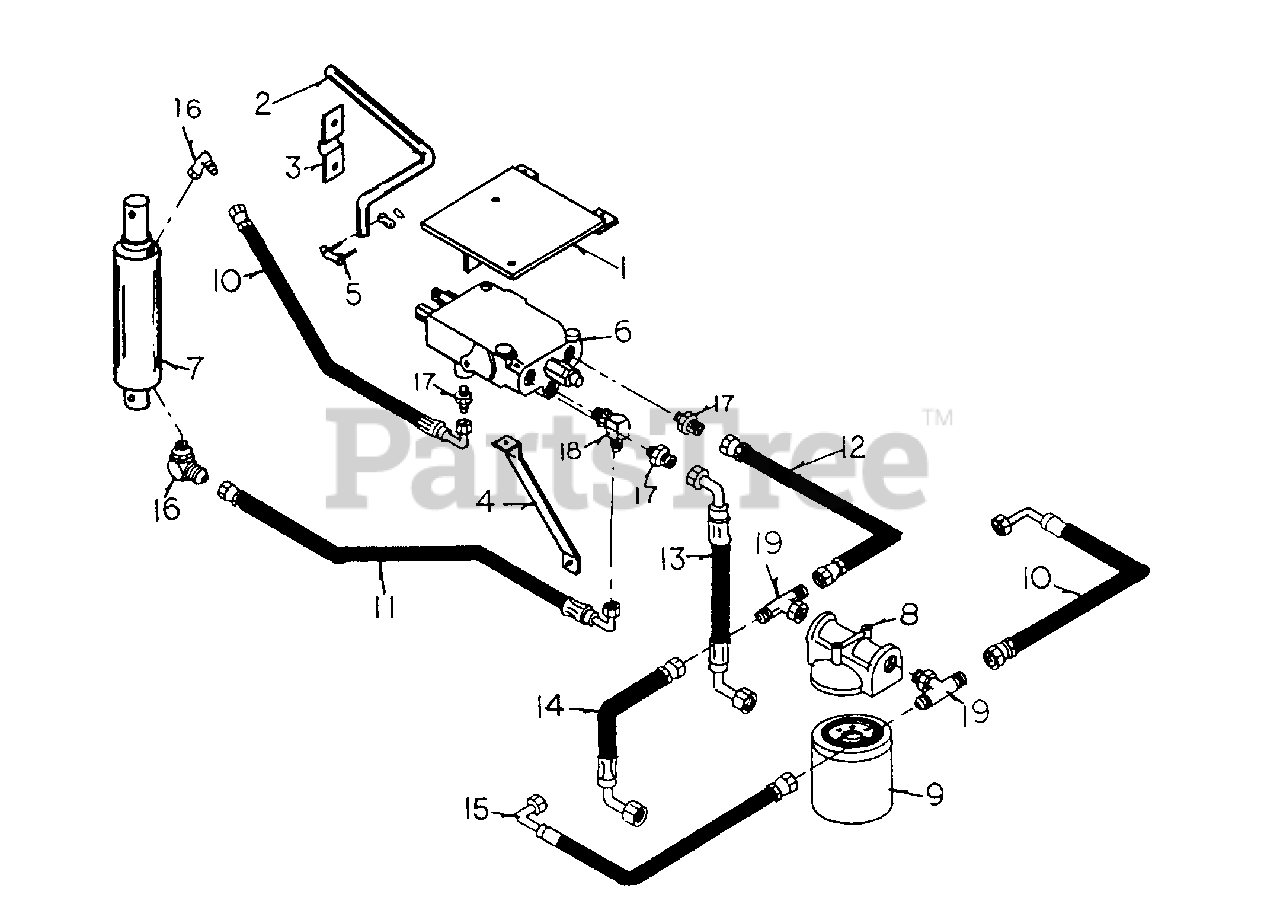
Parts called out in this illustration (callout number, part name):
1	MOUNT - valve
3	BEARING - clutch brake cross rod
4	SUPPORT - valve
5	CONNECTING LINK - #50
8	HOUSING - oil filter
9	ELEMENT - oil filter
10	HOSE - 3/8" ID x 26" long
11	HOSE - 3/8" ID x 31" long
12	HOSE - 3/8" ID x 20" long
13	HOSE - 3/8" ID x 13" long
14	HOSE - 3/8" ID x 11.5" long
15	HOSE - 3/8" ID x 21" long
16	FITTING - male o-ring, 90° male tube adp.
17	FITTING - male o-ring, male tube adp.
18	FITTING - male o-ring, 90° male tube adp.
19	FITTING - male tube, male o-ring tee
